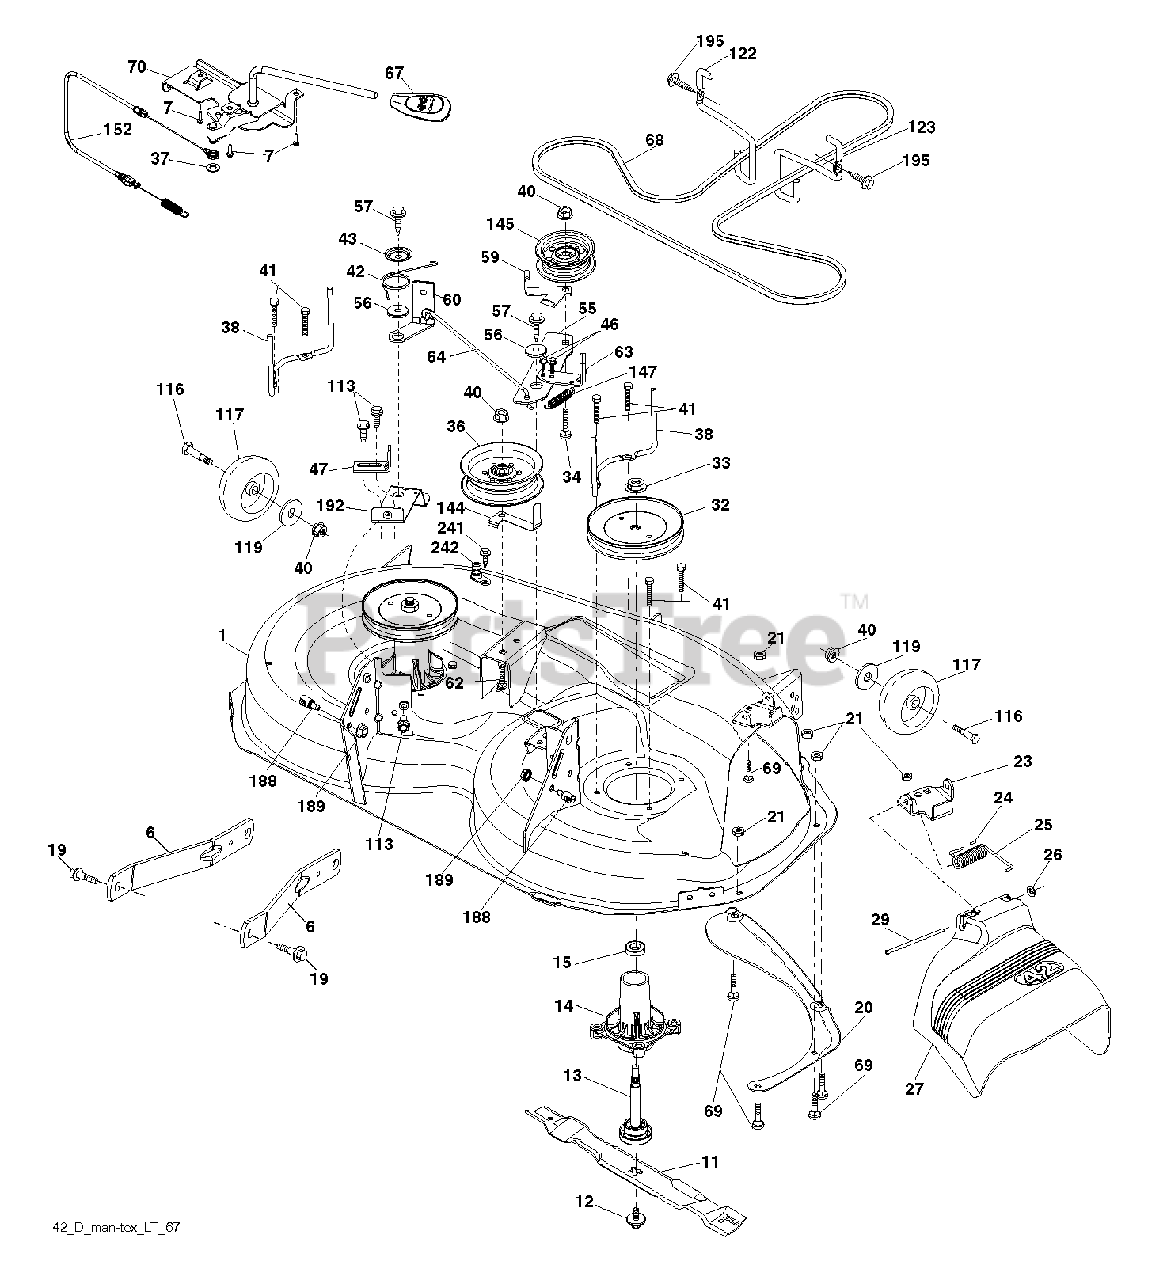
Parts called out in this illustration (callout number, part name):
1	DECK.WELDMNT.42"GREYMS498
6	ARM.SUSPENSION.MOWER.R
7	SCREW.#10 X 0.750.BOS
11	42" HI-LIFT BLADE
12	SCREW.SEMS.7/16-20X1.HEX.HEAD
13	SHAFT.ASM.MDRL.N/GREASE.38
14	HOUSING.MANDREL.4PT.
19	BOLT.SHOULDER
20	BAFFLE.VORTEX
21	LOCKNUT
23	BRKT.DEFLECTOR.38"2005+
24	CAP-SLEEVE LT
25	SPRING.TORSION.DEFLECT
26	NUT PUSH M
27	SHIELD.DEFLECTOR.MOWER.42"BLAC
29	ROD.HINGE
32	PULLEY.MANDREL.5.438.PD
33	NUT.FLANGE.LOCK.TOP
34	BOLT.3/8-16X1.50
36	PULLEY.IDLER.2006
37	WASHER
38	KEEPER.BELT.MANDREL.PULLEY
40	NUT LOCK FLG 3/8-16 UNC
41	BOLT.HEX.WASHR.HED.313-18X1.19
42	SPRING.TORSION.BRAKE
43	SRPING.TORSION.RETAINE
46	SCREW.1/4-20X5/8
47	BRKT.CLUTCH.CABLE
55	IDLER.ARM.42"
56	SPACER.RETAINER
57	SCREW 3/8-16X1
59	GUARD, BELT
60	ARM BRAKE MOWER
63	ARM BRAKE MOWER
64	LINKAGE.BRAKE.ASM.ZINC
67	HANDLE.CLUTCH.CABLE.LT
68	BELT.DECK.DRIVE.42"
69	BOLT
70	CLUTCH.ASM.MANUAL.YT.PREDATORQ
113	BOLT.5/16HEX.WHS.HD
116	BOLT M
117	WHEEL.GAGE.HALF.SPOKED
119	WASHER
122	KEEPER BELT ENGINE LH
123	KEEPER BELT RH
144	KEEPER.BELT.MOWER
145	PULLEY.IDLER.48"PRIMARY
147	RETURN SPRING
152	CABLE.CLUTCH.CABLE.W/SPRING
188	STUD.FASTNER.W/ANTI-ROTATE
189	NUT LOCK HEX FLANGE 5/16-18
192	BRKT.BRAKE.STAND.LH.
195	SCREW, 3/8-16X3/4
241	SCREW.TT.#10-32X.5.3/8.FLANGE
242	PORT.WASHOUT
